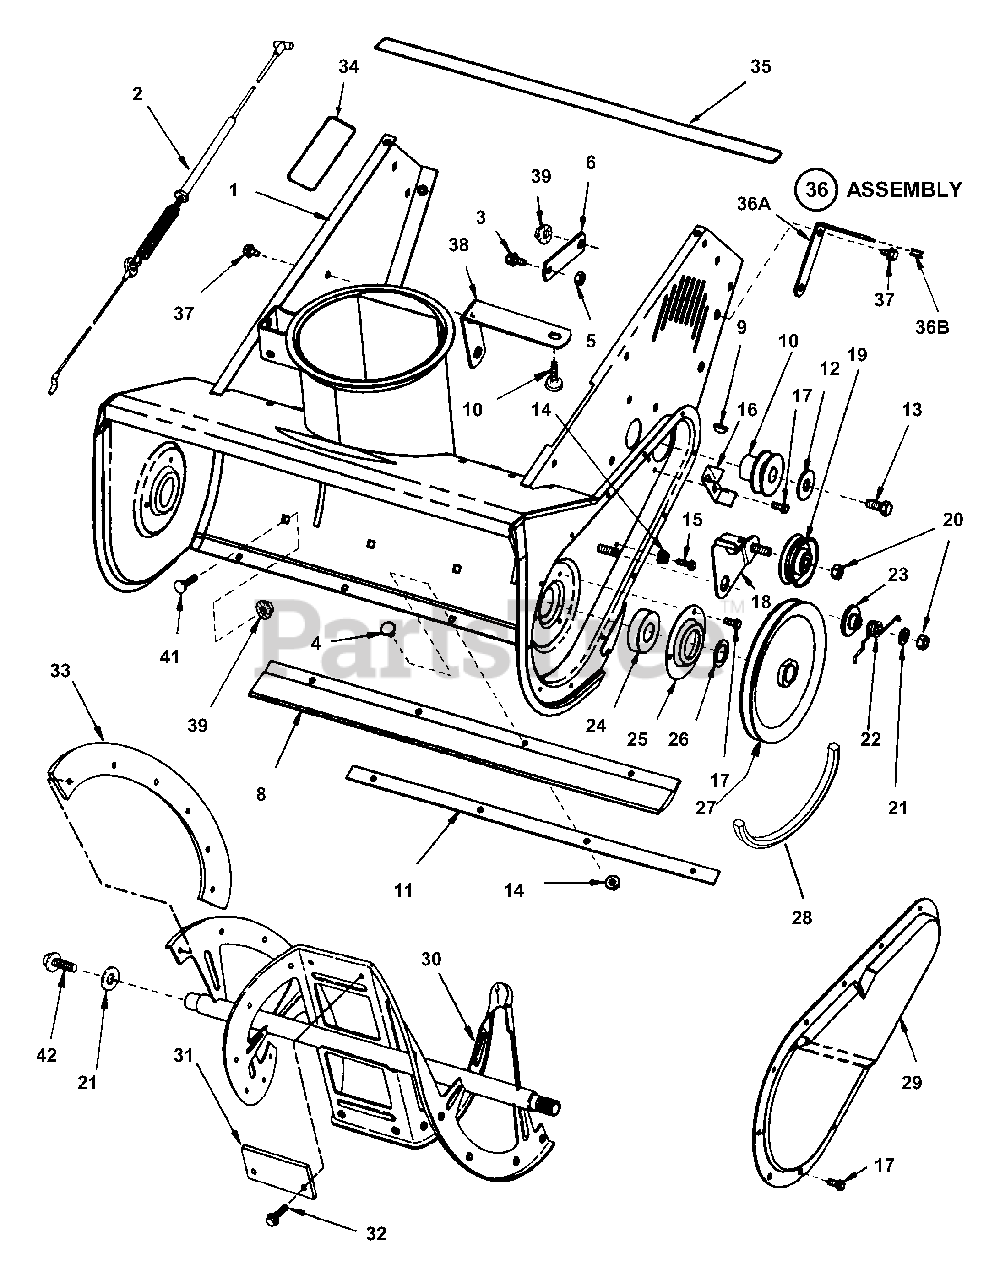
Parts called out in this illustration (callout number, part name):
1	WELDMENT, Blower Housing
2	CABLE, Clutch
3	BOLT, 1/4-20 x 1/2" Hex Flange Lock
4	BOLT, #10-24 x 5/8" Flat Head Carriage
5	NUT, 1/4-20 Hex Center Lock
6	STRAP, Engine
8	SCRAPER, Blade
9	KEY, (#6) 5/32 x 5/8" Woodruff
10	PULLEY, Engine
11	BLADE, Wear Indicator
12	WASHER, .343 I.D. x 1" O.D. Flat
13	SCREW, 5/16-24 x 3/4" Hex Head Cap w/patch lock, Grade 5
14	NUT, #10-24 Hex Flange Lock
15	SCREW, #10-24 x 5/8" Self-Tap
16	GUIDE, Belt
17	SCREW, #10-32 x 1/4" Slotted Hex Washer Head, Self-Tap
18	ASSEMBLY, Idler Arm
19	PULLEY, Idler Arm
20	NUT, 5/16-18 Hex Center Lock
21	WASHER, 5/16 Flat
22	SPRING, Idler Brake
23	SPACER, Bearing
24	BEARING, Auger
25	RETAINER, Bearing
26	WASHER, 3/4" Flat
27	PULLEY
28	BELT, Auger 32.89
29	COVER, Belt
30	AUGER Structure 20"
31	SHOE, Flight, Center
32	SCREW, #10-24 x 1/2" Hex Washer Self-Tap (Sems)
33	SHOE, Flite
34	DECAL, Model (Recoil)
35	DECAL, Model, Auger Housing (Recoil)
36	ASSEMBLY, Bracket/Bushing
36A	BRACKET, Cable Guide
36B	BUSHING, Nylon
37	SCREW, 1/4-20 x 3/8" Hex Washer Self-Tap
38	BRACKET, Fuel Tank
39	NUT, 1/4-20 Hex Flange Lock, Grade 5
41	BOLT, 1/4-20 x 1/2" Short Neck Carriage, Grade 5
42	SCREW, 5/16-18 x 5/8" Hex Washer Self-Tap
